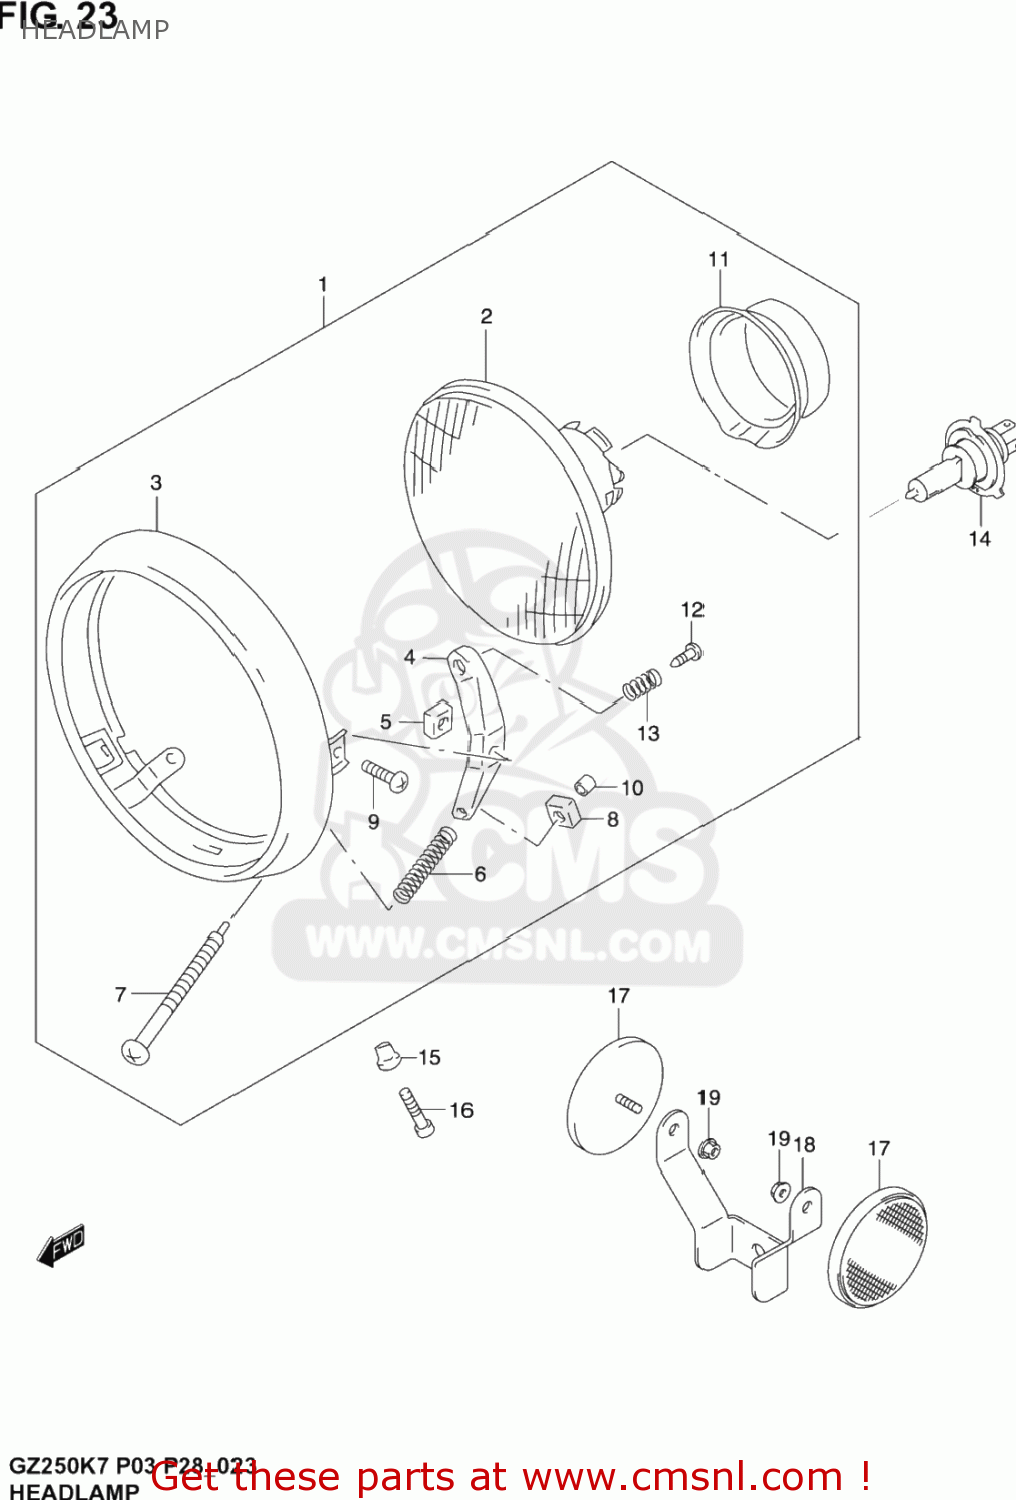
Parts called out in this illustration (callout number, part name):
1	HEADLAMP ASSY
2	UNIT ASSY
3	RIM,HEAD LAMP
4	STAY
5	NUT
6	SPRING
7	SCREW
8	NUT,HEADLAMP ADJUST
9	SCREW
10	CAP,SCREW
11	COVER,SOCKET
12	SCREW
13	SPRING
14	BULB(12V60/55W,H4)
15	SPACER,HEADLAMP
16	SCREW
17	REFLECTOR
18	BRACKET,FR SIDE DEFLECTOR
19	NUT, LICENSE
